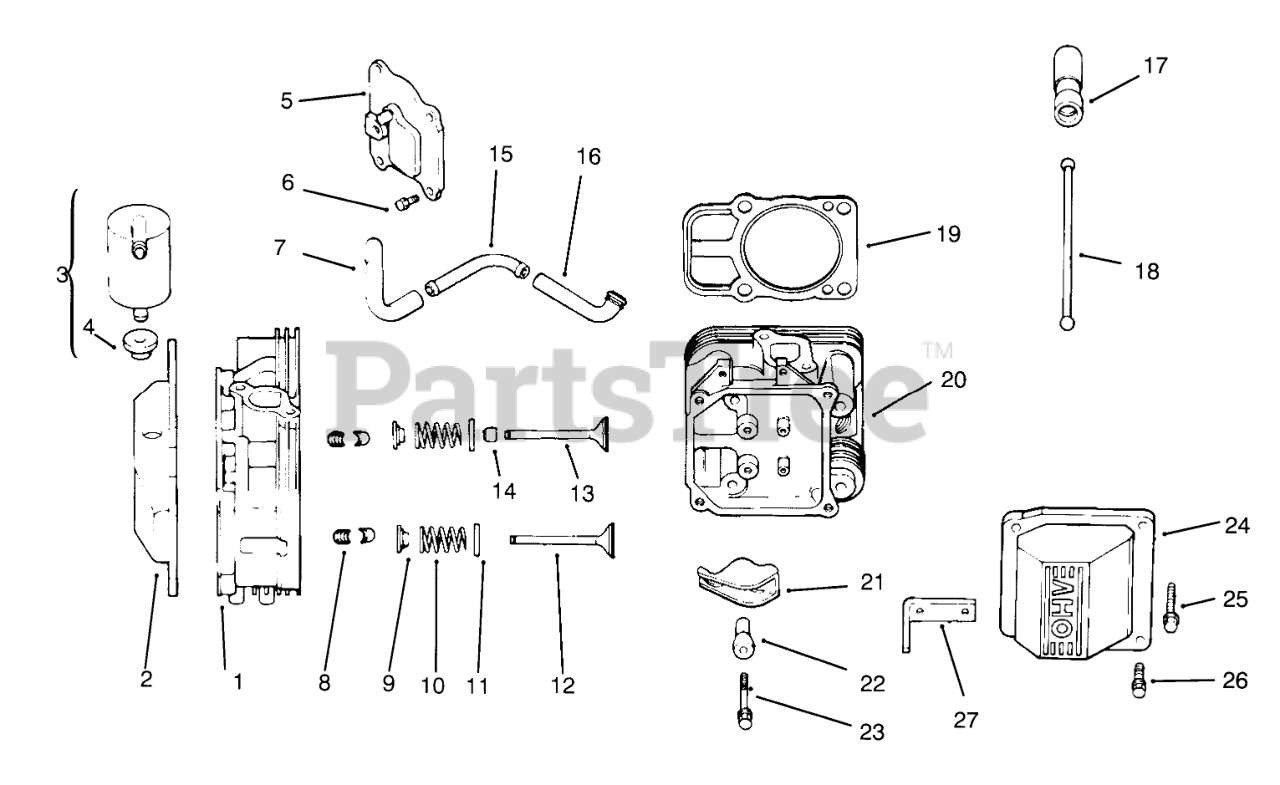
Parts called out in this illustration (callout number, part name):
1	Head ASM-#1 Cylinder
2	Cover-Rocker
3	Kit-Breather INC 4
4	Grommet-Rubber
5	Cover-Breather
6	Screw
7	Hose-Breather
8	Retainer Kit
9	Cap-Spring, Valve
10	Spring-Valve
11	Retainer-Spring
12	Valve-Exhaust
13	Valve-Intake
14	Seal-Stem, Valve
15	Fitting
16	Hose-Breather
17	Lifter-Valve
18	Rod-Push
19	Gasket-Cylinder Head
20	#2 Cyl. Head Asm,
21	Arm-Rocker
22	Pivot-Rocker Arm
24	Cover-Rocker
25	Screw
26	Screw
27	Strap-Lifting
